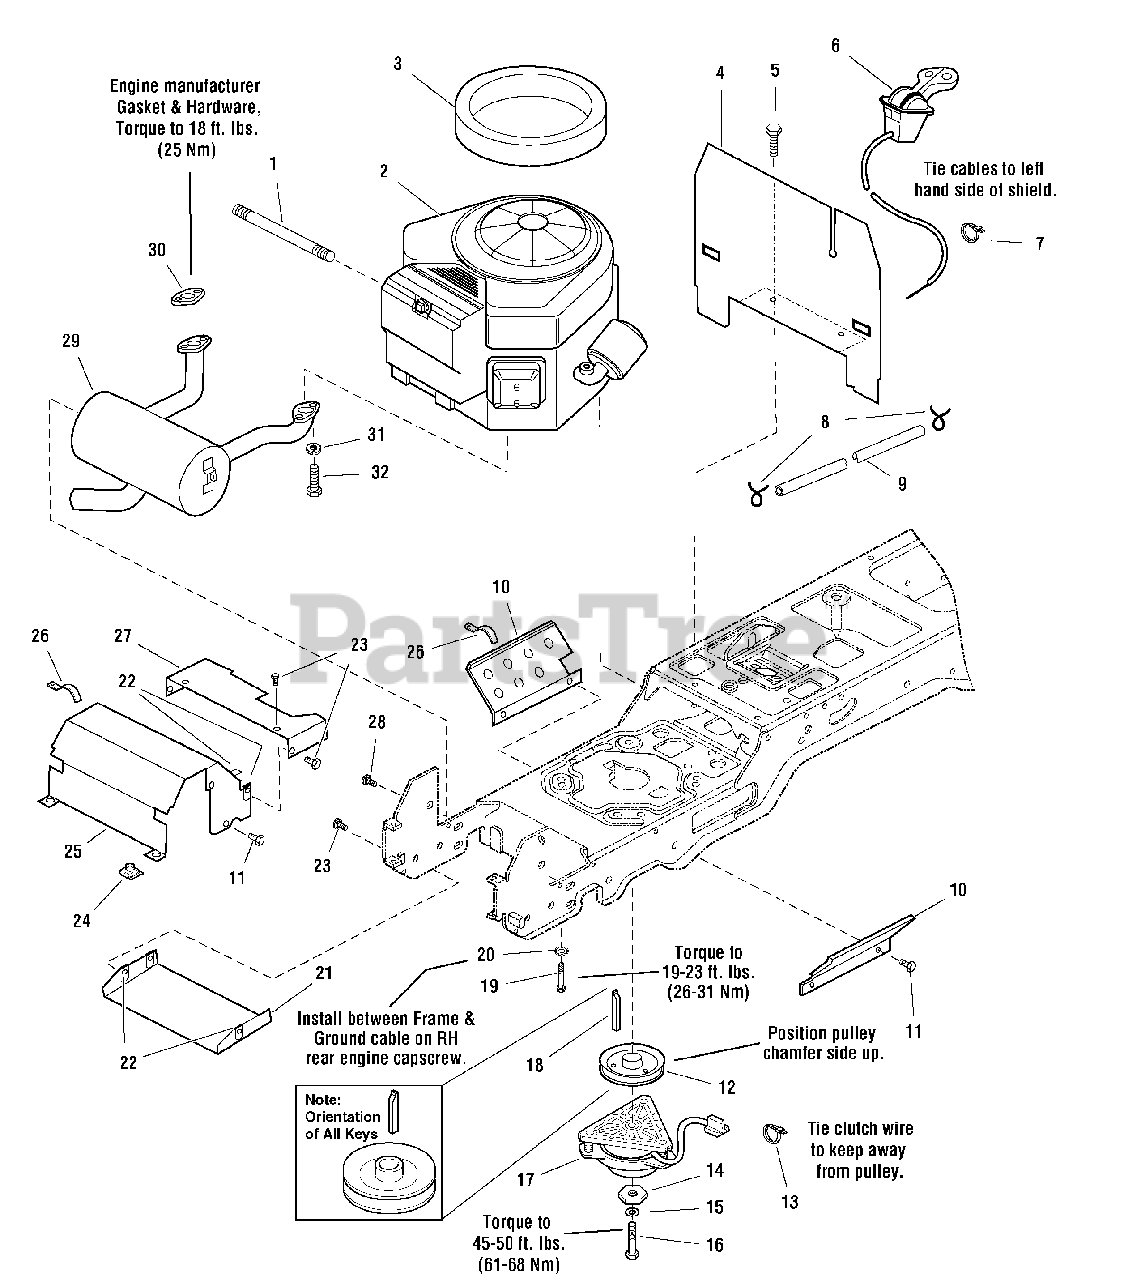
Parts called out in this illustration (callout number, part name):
1	HOSE, Oil Drain, 10 1/2 Long, 3/8-18 Fittings
3	SEAL, Circle
5	CAPSCREW, Hex Washer Head Taptite, 1/4-20 x 1/2, Black
6	CONTROL, Throttle Double, 39" Long, w/Knobs
8	CLAMP, Hose Type E
9	HOSE, Fuel, 58 Long
10	SHIELD, Side
11	CAPSCREW, Hex Washer Head Taptite, 1/4-20 x 3/8
12	PULLEY & HUB ASSEMBLY
13	TIE, Self Locking, 3-5/8 Long
14	WASHER, Hex, 7/16, Black
15	LOCKWASHER, 7/16
16	CAPSCREW, Hex Head, 7/16-20 x 3-1/2
17	CLUTCH, Electric
18	KEY, HI PRO, 1/4 x 2-1/2
19	CAPSCREW, Hex Washer Head Taptite, 3/8-16 x 1-1/2
20	LOCKWASHER, External Tooth, 3/8
21	SHIELD, Muffler Bottom
22	NUT, Speed, 1/4-20, Lug, Black
23	CAPSCREW, Hex Flange Whiz Lock, 1/4-20 x 5/8
24	NUT, Speed 5/16-18, Lug, Black
25	DUCT, Muffler Top
26	CLIP, Wire 1/8, Panel
27	DUCT, Muffler Extension
28	CAPSCREW, Hex Washer Head Taptite, 5/16-18 x 1/2, Black
29	MUFFLER, B&S Vanguard Twin
30	GASKET, Briggs & Stratton, Vanguard Twin
31	LOCKWASHER, 1/4
